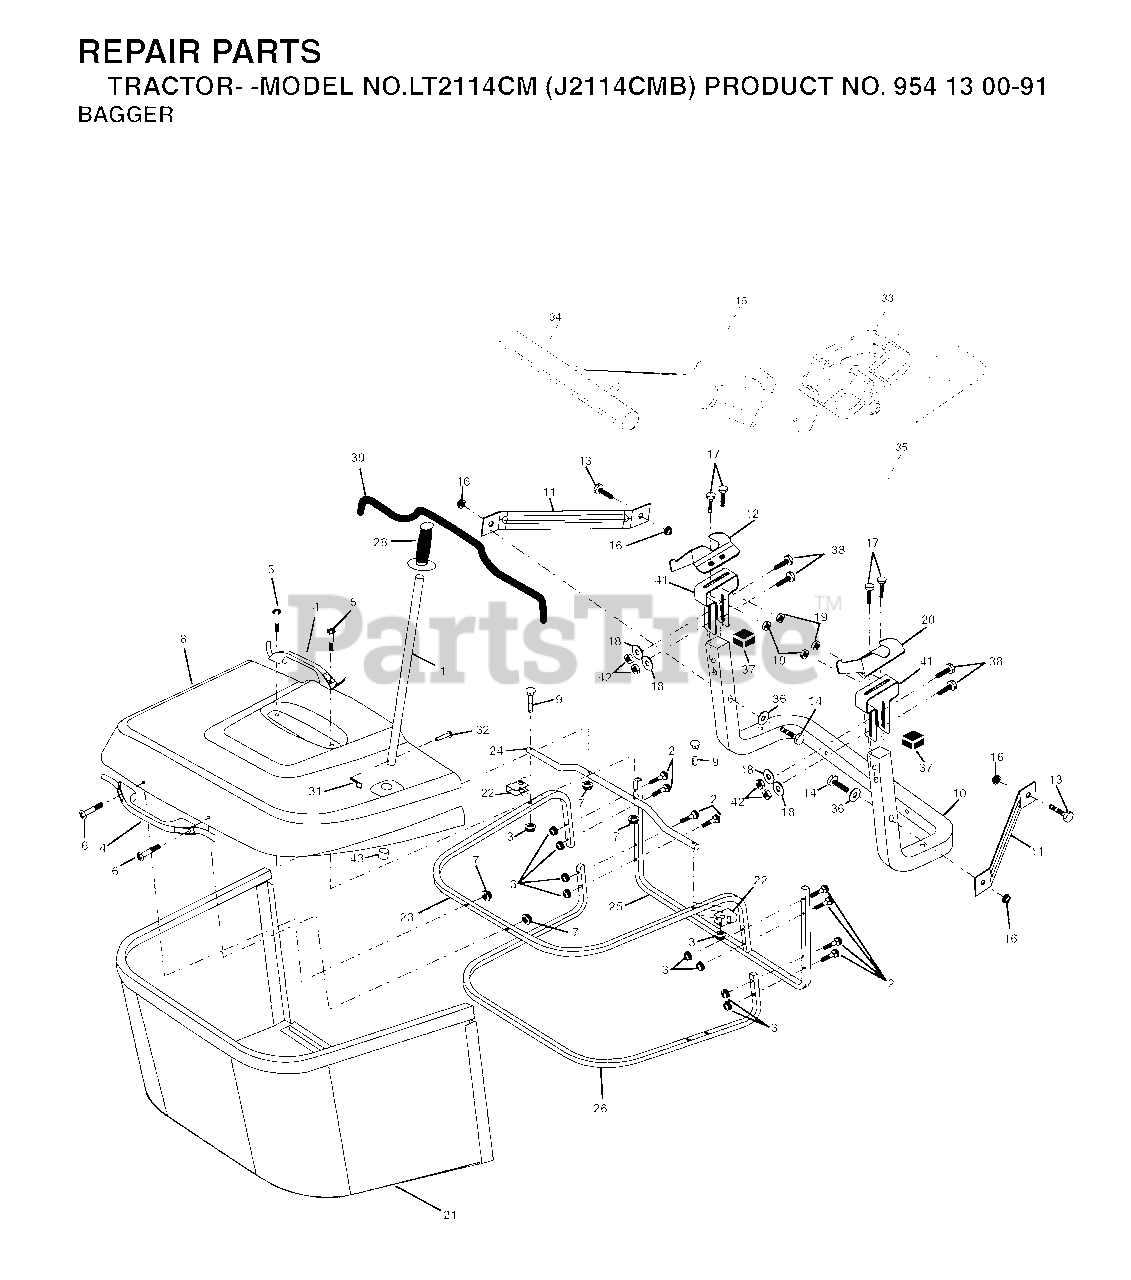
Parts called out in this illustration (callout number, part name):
1	TUBE HANDLE
3	NUT T
5	SCREW.PAN.HEAD
11	BRACKET
14	BOLT-HEX EAK
15	RETAINER-SPRNG RB
16	NUT LOCK FLG 3/8-16 UNC
17	BOLT
18	WASHER M
19	NUT LOCK HEX FLANGE 5/16-18
20	BRACKET
21	GRASS BAG
22	BRACKET
23	TUBE
24	TUBE
26	TUBE
28	GRIP.HANDLE.BLACK
31	RETAINER CLIP
32	RIVET,DRILLED
33	PLUG
35	PIN
36	WASHER
38	BOLT.5/16-18X2.5
41	BRKT, BAGGER
42	NUT.71038.31-18.HEX.NYLOCK
43	PLUG, TUBING END
